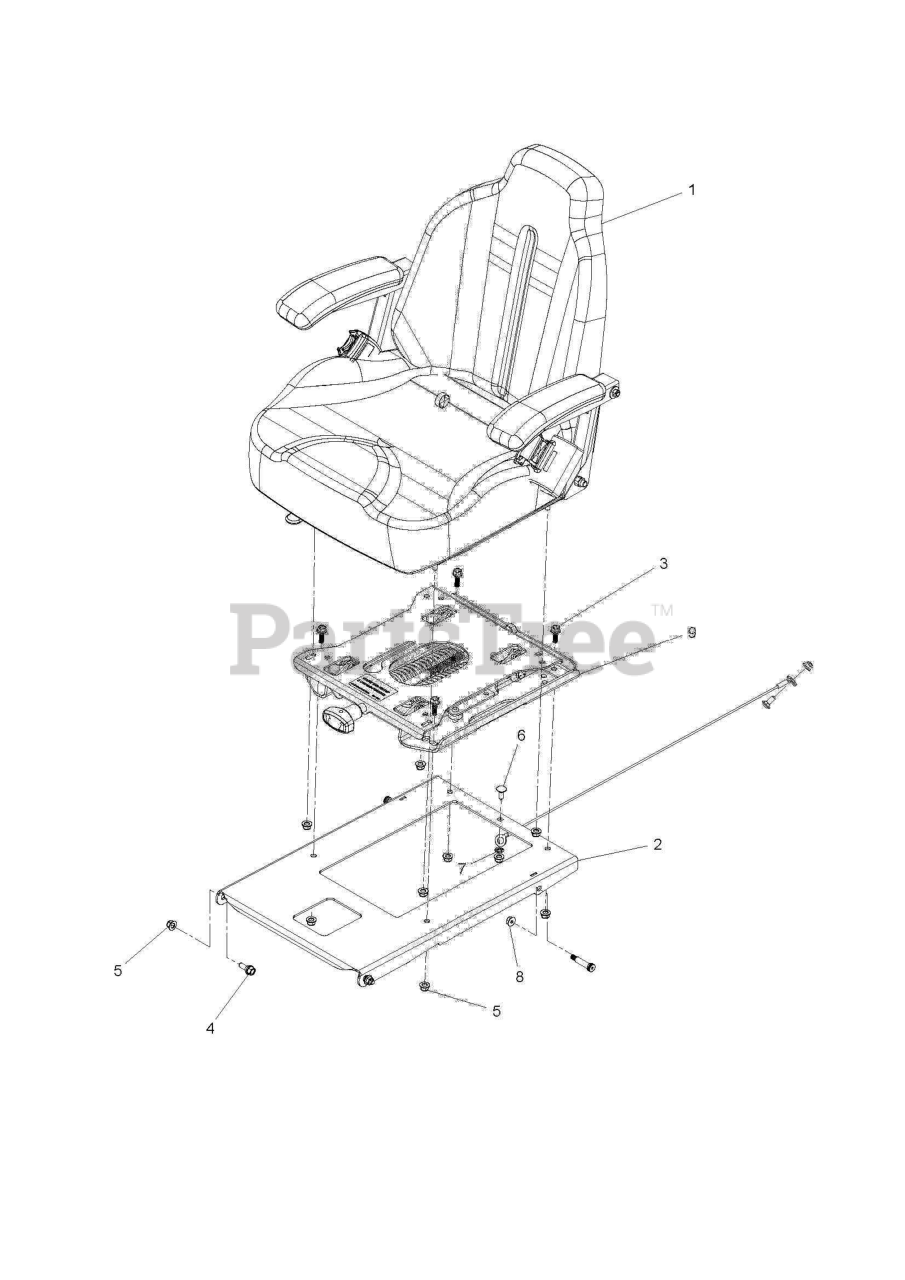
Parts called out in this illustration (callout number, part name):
4	SB 5/16-18 HEX HD GD5, BLK ZN
5	NUT HEXAGON FLANGE 5/16-18 ST
6	GSPW Bolts
7	WASHER 5/16"
